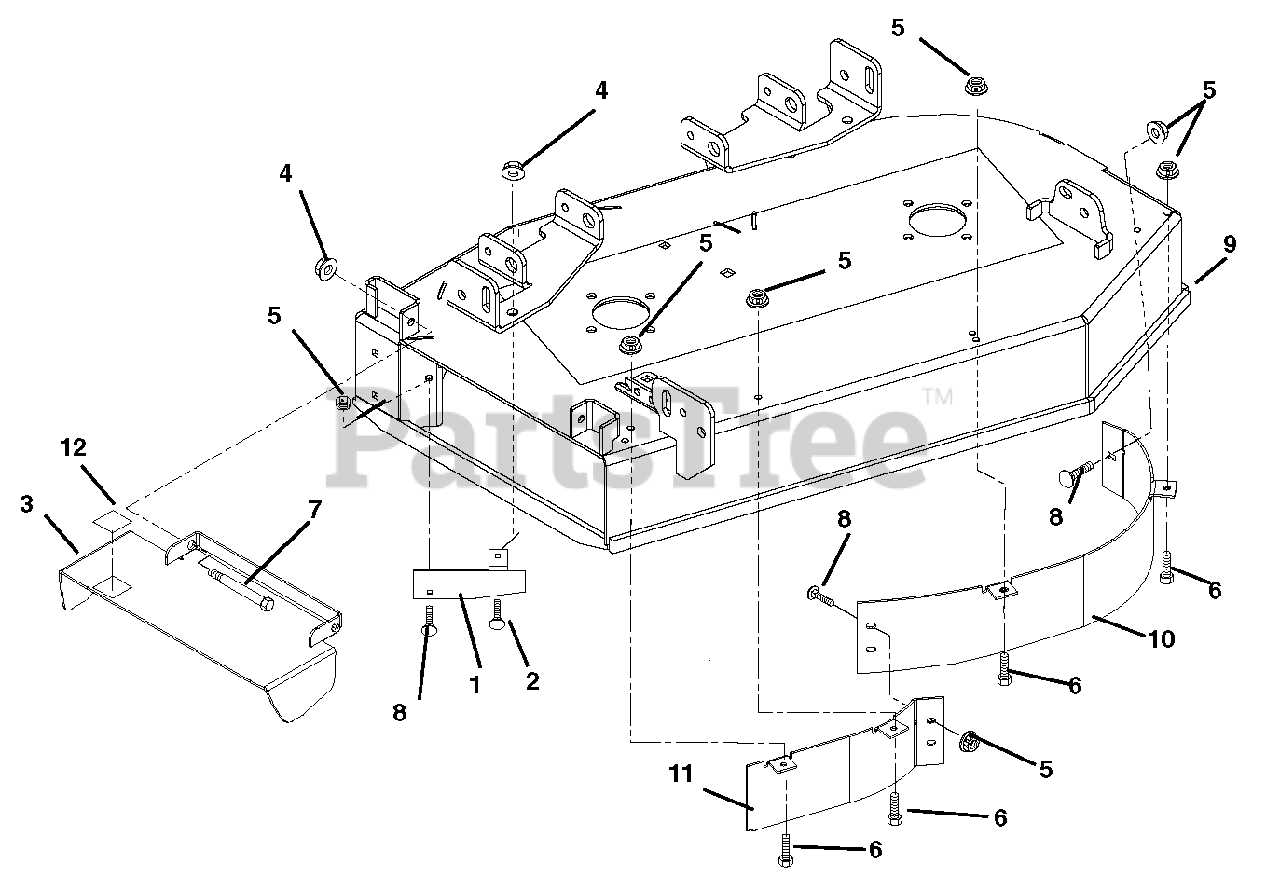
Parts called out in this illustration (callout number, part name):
1	Baffle, Deflector
2	Bolt, Round Head Square Neck .38-16 x 1.25 Grade 5
3	Chute, Discharge
4	Nut, Nyloc Flange 3/8-16
5	Nut, Nyloc Flange 5/8-18
6	Bolt, Hex .31-18 x .75 Grade 5
7	Bolt, Shoulder .38-16 x .50 Socket Head
8	Bolt, Round Head Square Neck .31-18 x .75 Grade 5
9	Weldment, 34" Side Discharge Deck
10	Baffle, 34" Front Left Hand
11	Baffle, 34" Front Right Hand
12	Grip, Pedal 1.50 x 3.00
